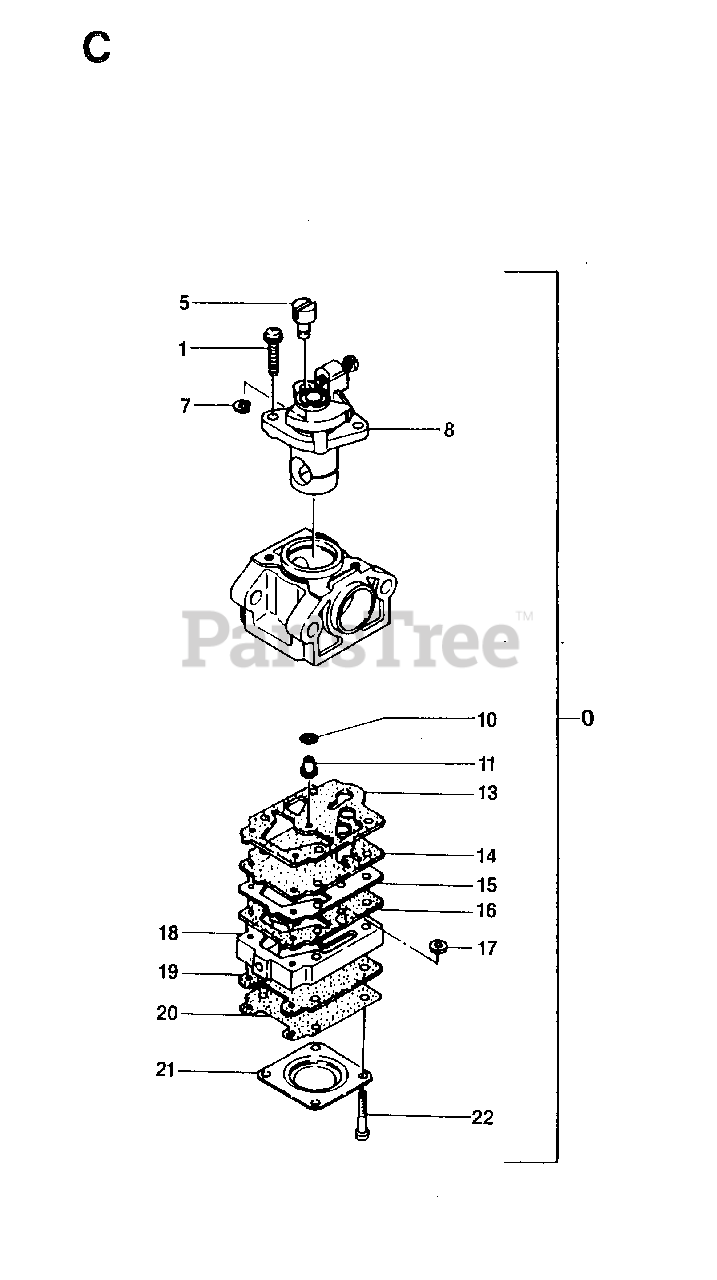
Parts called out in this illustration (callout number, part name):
7	RETAINING RING
8	THROTTLE VALVE CPL.
18	PUMP BODY COMP.
20	METERING DIAPHRAGM
